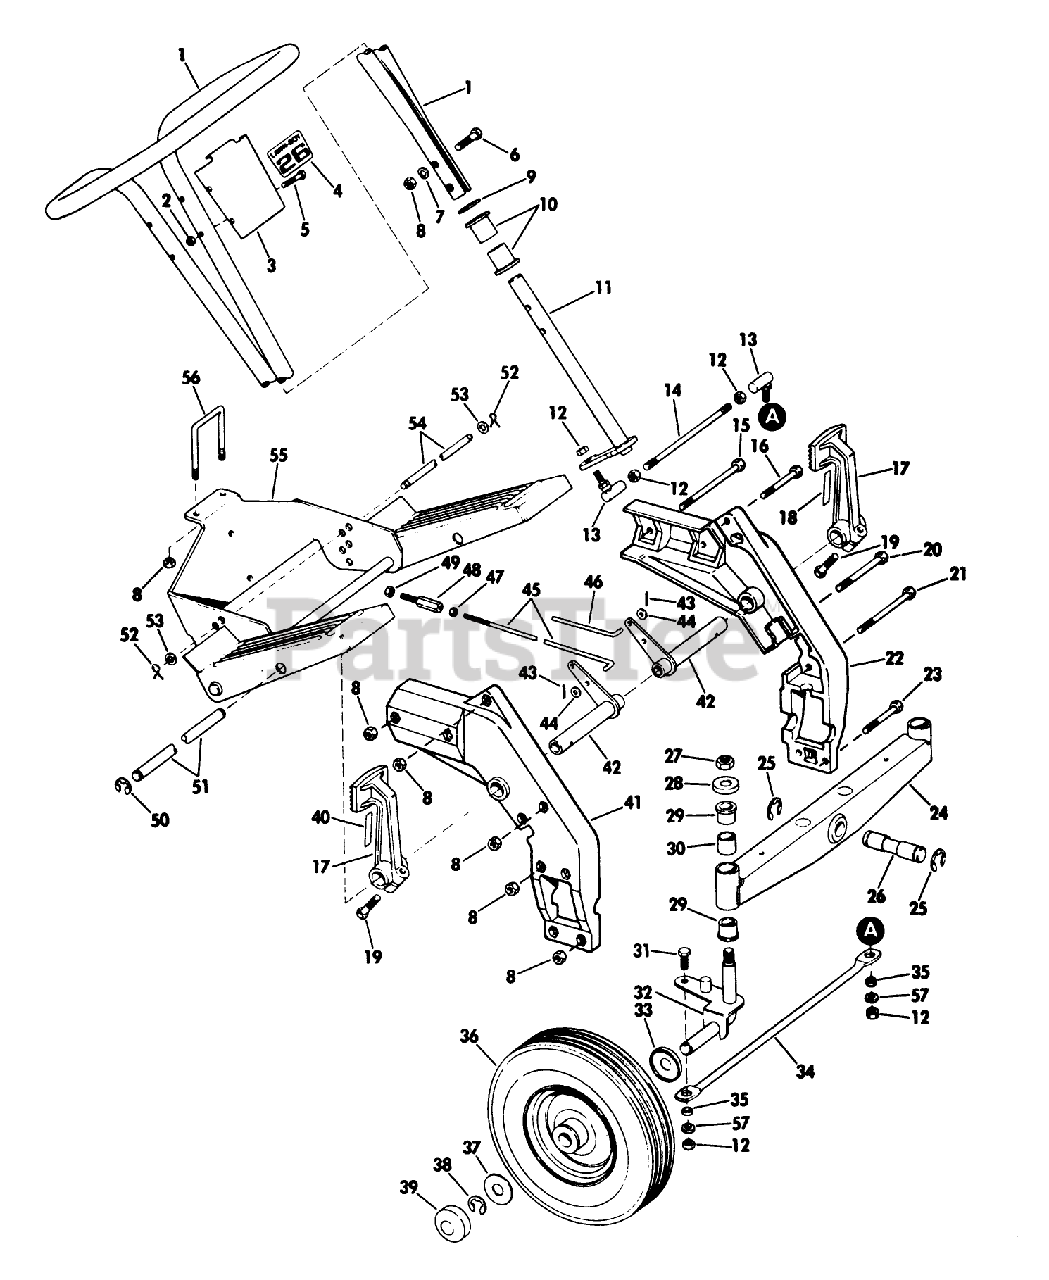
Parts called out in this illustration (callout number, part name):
2	STOP NUT
7	Lockwasher
16	Screw-Seat Support
31	Screw-King Pin
52	HAIR PIN
